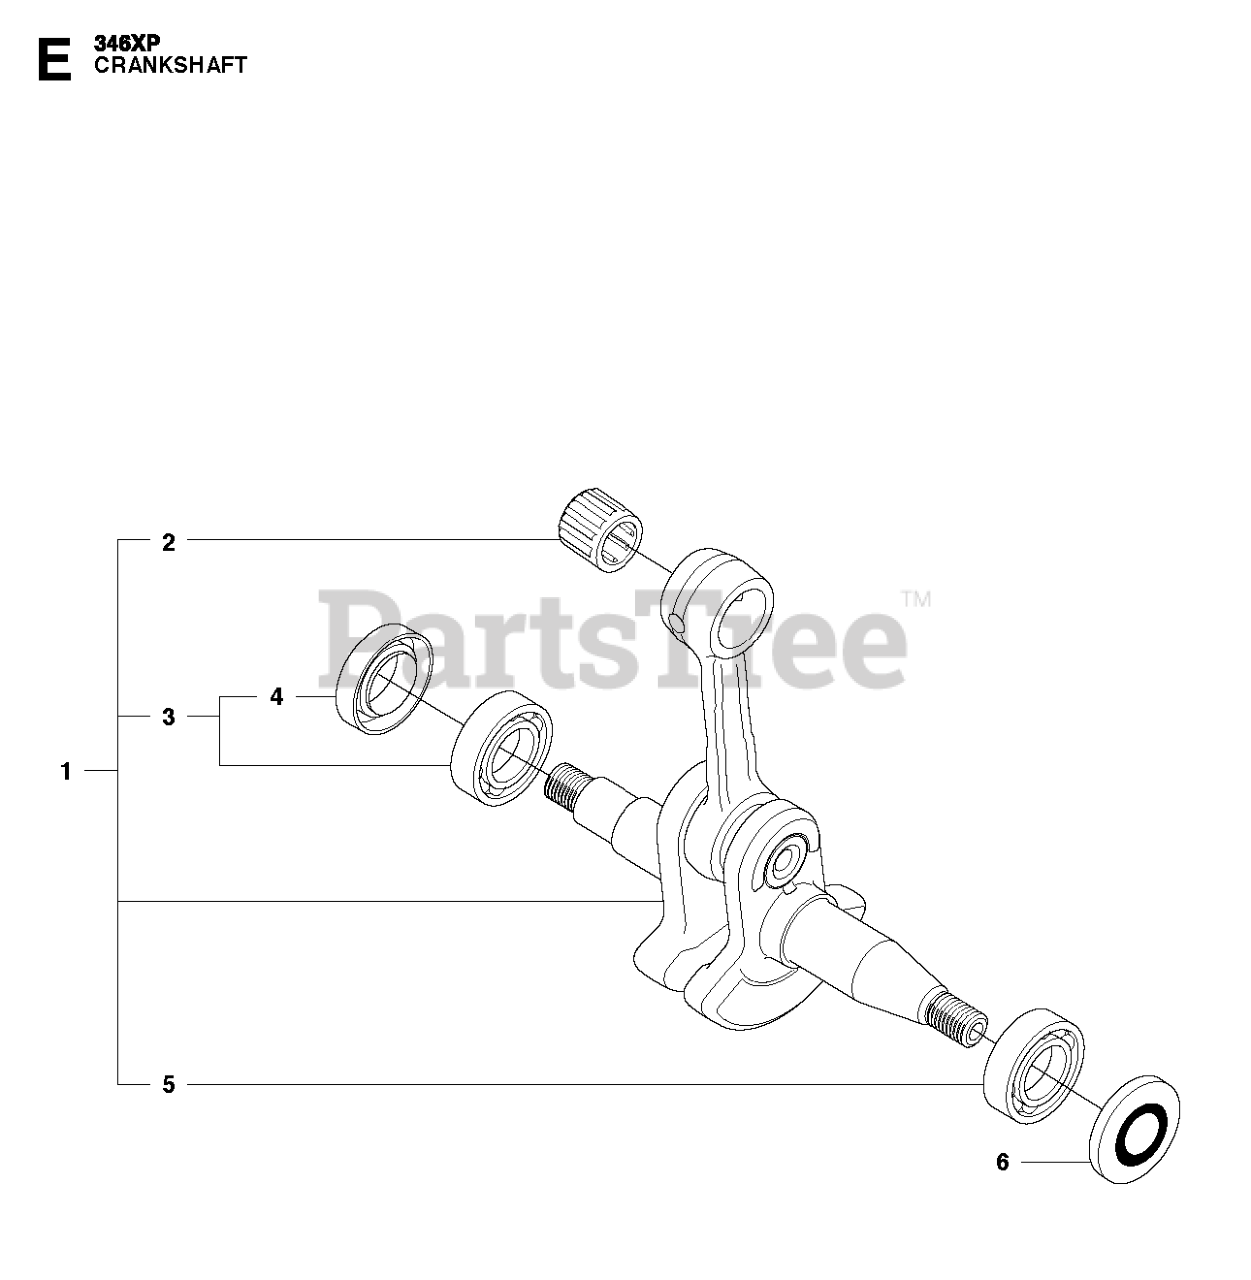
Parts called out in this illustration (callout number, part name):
1	CRANKSHAFT
2	SUPPORT BUSHING
3	BALL BEARING
4	RADIAL SEAL
5	BALL BEARING-6202-C3 SKF
